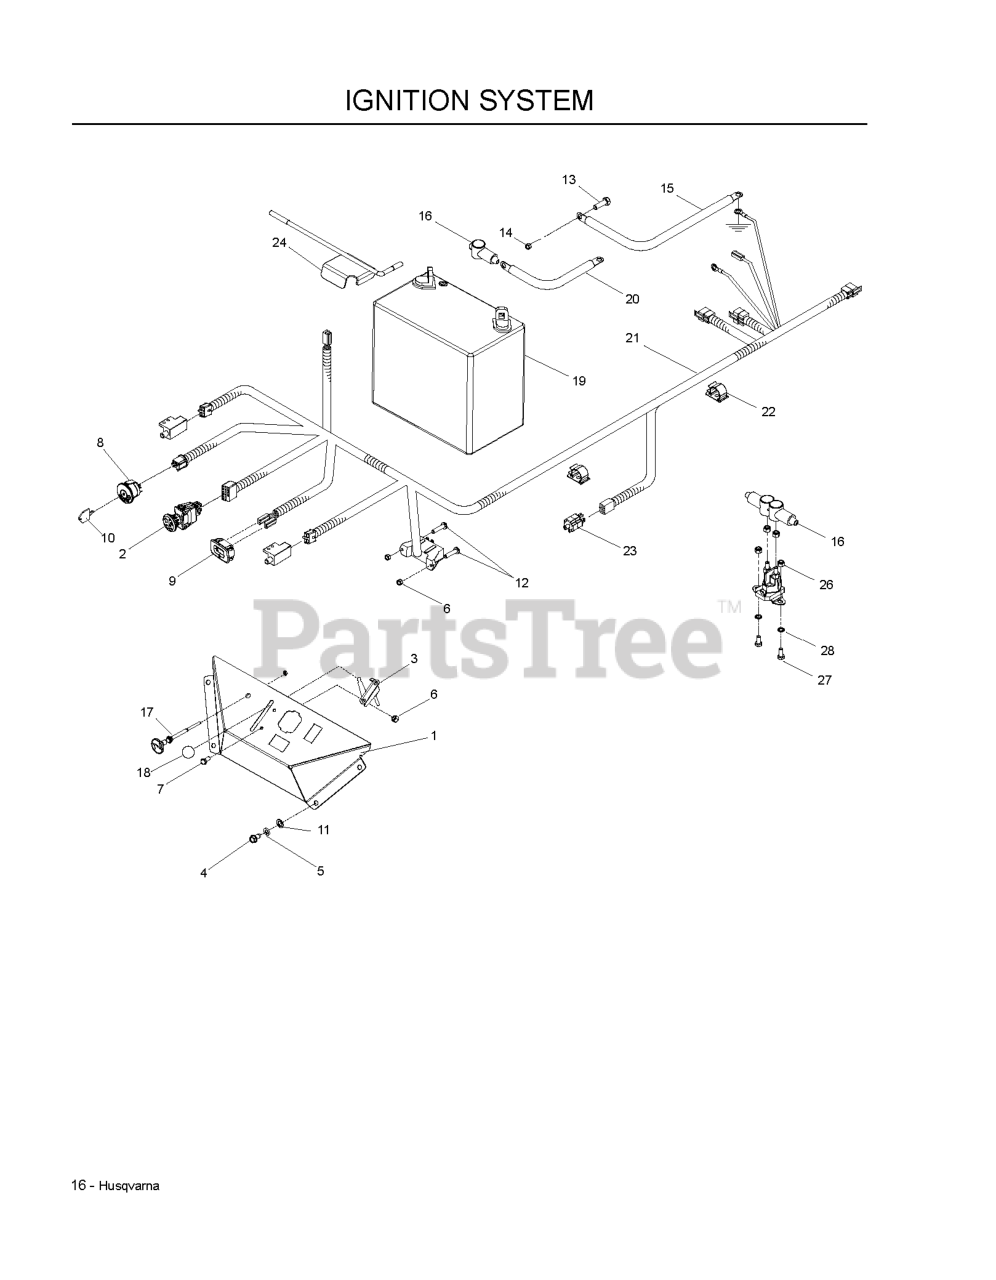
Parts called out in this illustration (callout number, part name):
1	CONSLE, ORANGE
2	RP SWITCH.PTO.TERMINAL.STD.RED
3	THROTTLE CABLE
4	SCREW 1/4 X 5/8
5	LOCKWASHER 1/4"
6	NUT 10-24 NYLOC
7	HCS #10-24 X 1/2
8	RP IGNITION SWITCH
9	HOUR METER
10	KEY
11	WASHER 1/4 FLAT
12	SCREW, #1--24 X 1/2 SLOTTED
13	HCS 5/16C X 3/4
14	NUT 5/16 NYLOC
15	CABLE-NEGATIVE
17	CONTROL-CHOKE 51"
19	BATTERY, 12 V 330 AMP
20	CABLE POSITIVE, LONG
21	HARNESS, WIRING LZ/IZ
22	PUSH-MOUNT WIRE CLIP
23	SWITCH, BRAKE 3P
24	BATTERY HOLD DOWN
25	SOLENOID
26	NUT.1/4-20.HEX.NYLOC.ZD
27	HCS 1/4C X 5/8
28	WASHER 1/4 INT TOOTH
